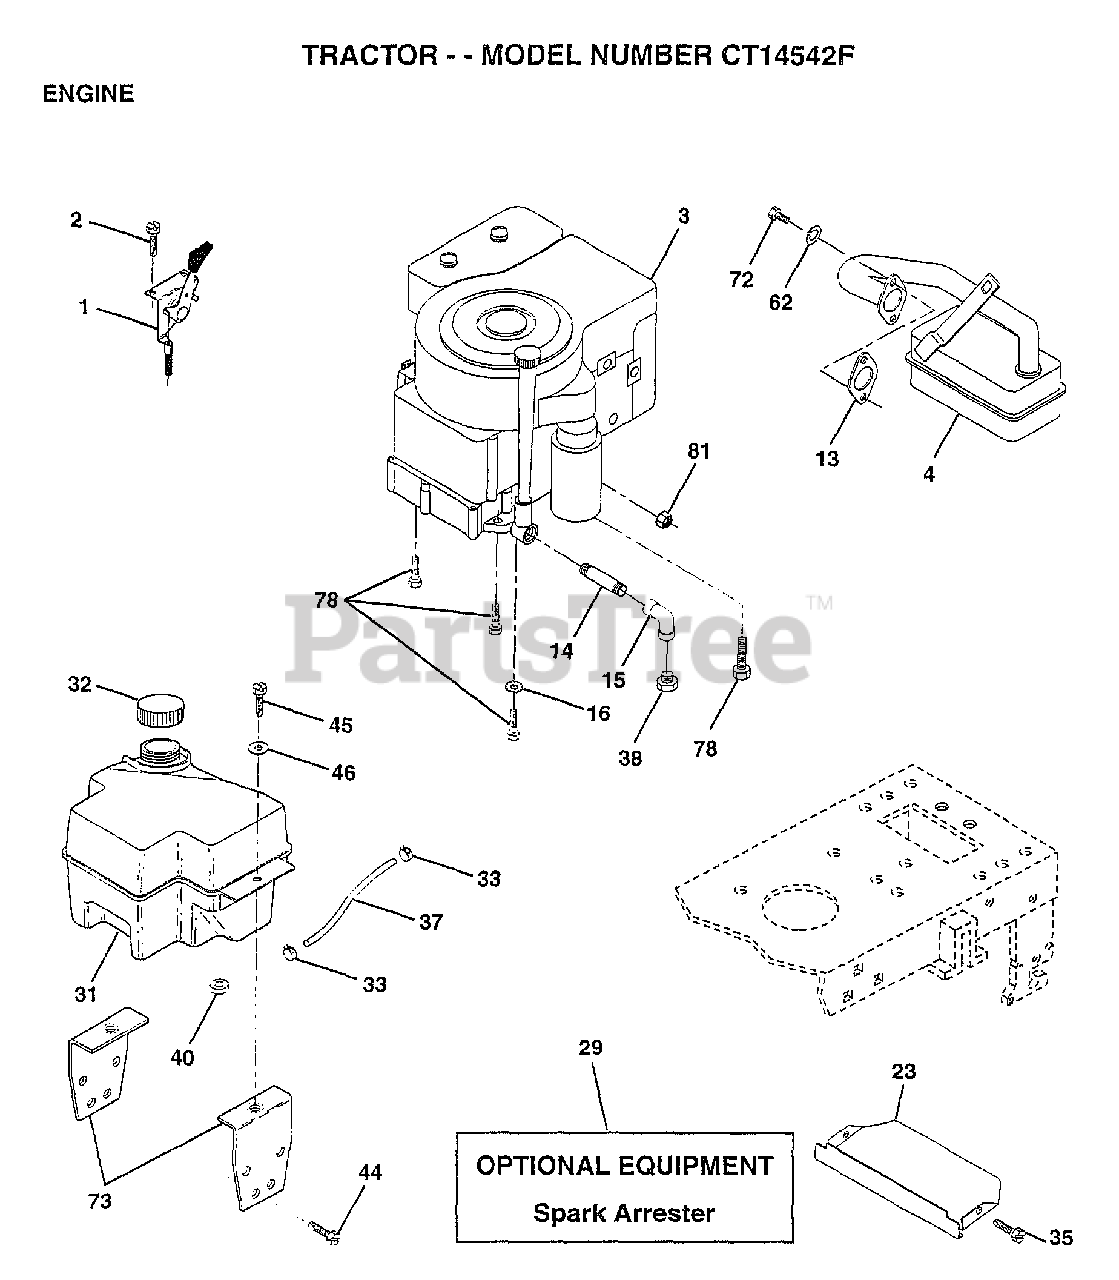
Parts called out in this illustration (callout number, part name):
1	CONTROL.THTL.19.6
2	SCREW LT
4	MUFFLER
13	GASKET ENG 1 313 LD TIN PLATED
14	PIPE NIPPLE
15	ELBOW
16	LOCKWASHER
23	SHIELD.BRN/DBR.GD
31	TANK.FUEL.FRONT.
32	CAP ASM FUEL
33	HOSE CLAMP
35	SCREW
37	LINE FUEL
44	SCREW
45	SCREW HEX CRT
46	WASHER
62	LOCKWASHER
72	SCREW
73	BRACKET.SUPT.TANK
78	SCREW
81	NUT
